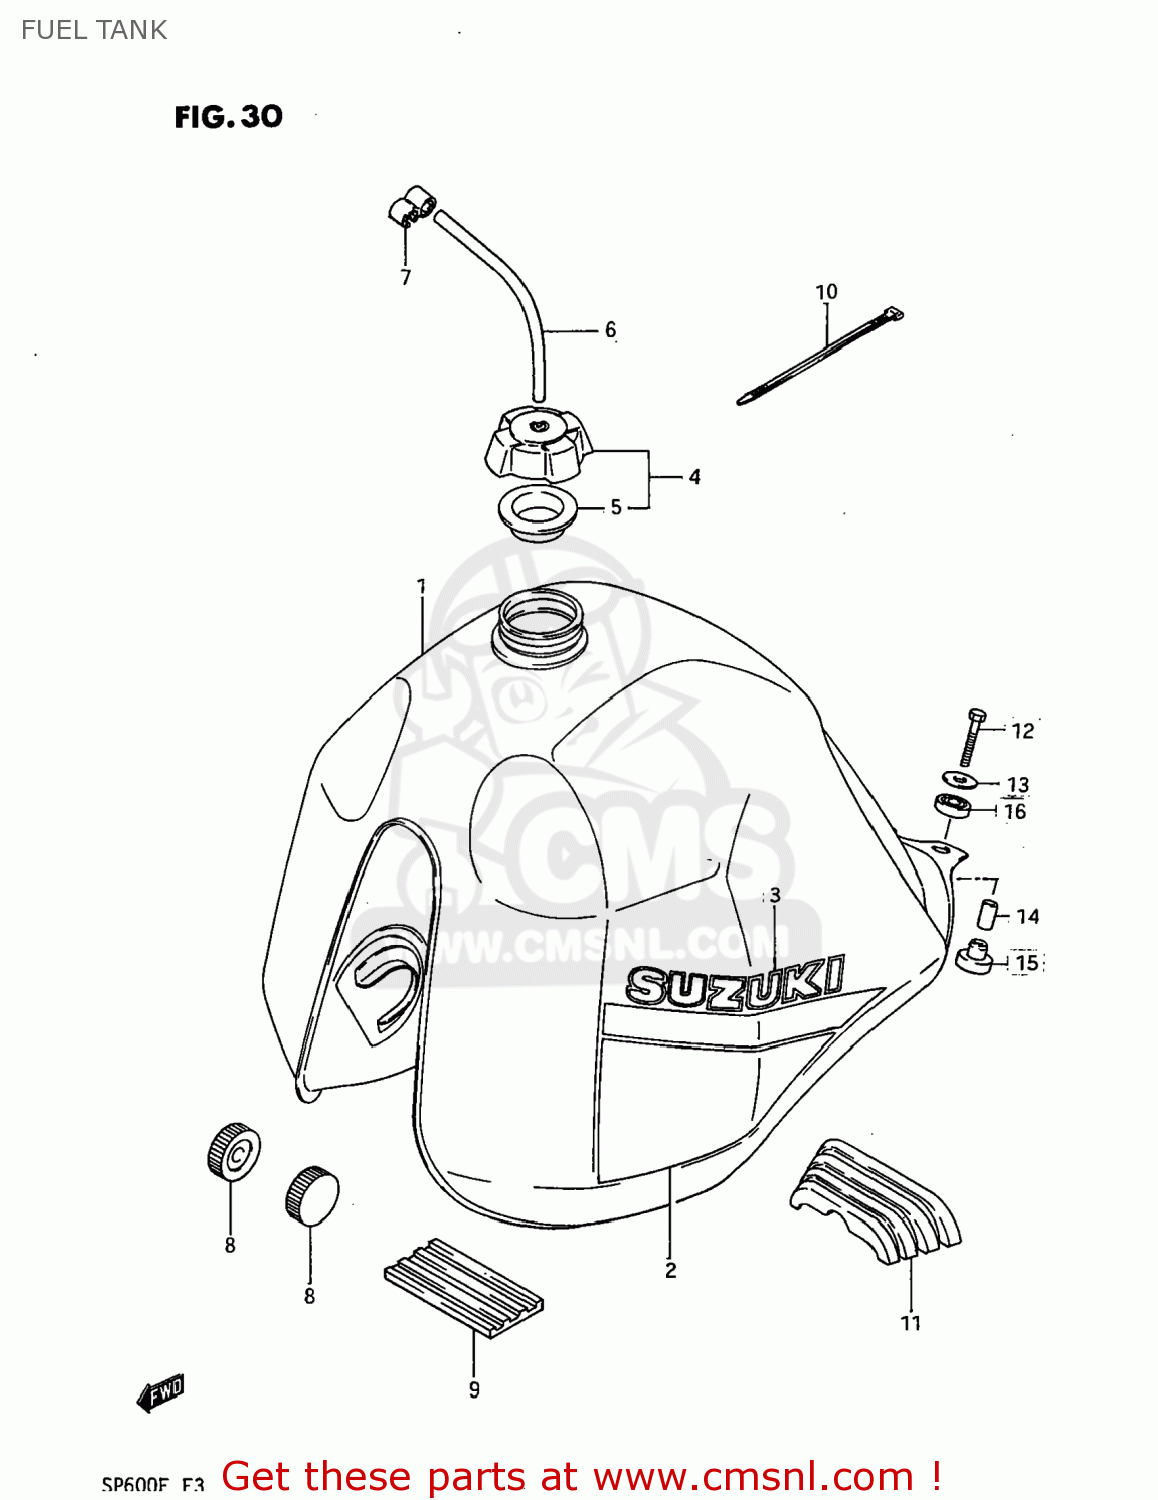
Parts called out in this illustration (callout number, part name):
1	TANK ASSEMBLY,FUEL
2	TAPE SET,FUEL TANK
3	EMBLEM
4	CAP SET,FUEL TANK
5	GASKET,FUEL TANK CAP (NAS)
6	HOSE
7	CLAMP,FUEL TANK BREATHER HOSE
8	CUSHION
9	CUSHION,FUEL TANK UPR FR
10	CLAMP
11	CUSHION,FUEL TANK RR
12	BOLT
13	WASHER (6.5X24X1.6)
14	SPACER
15	CUSHION
16	CUSHION
